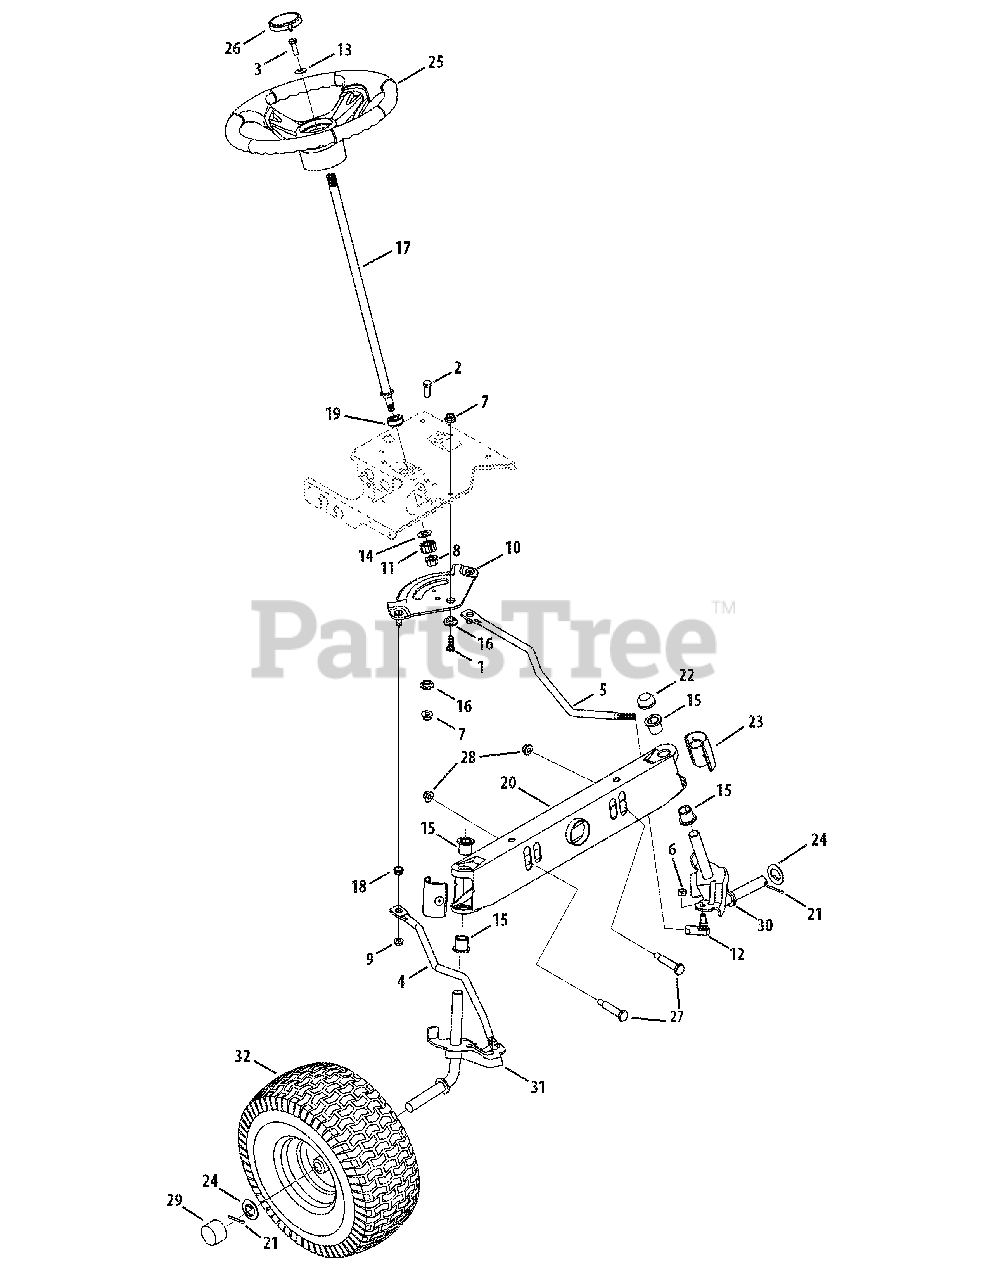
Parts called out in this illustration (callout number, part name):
1	Hex Screw, 3/8-16, 1.00, Gr5
2	Hex Screw, 3/8-16, 1.00, Gr5
3	Hex Screw, 5/16-18, 1.00, Gr5
4	Link, Drag, RH
5	Link, Drag, LH
6	Nut, Hex Lock, 3/8-24
7	Nut, Flange Lock, 3/8-16, Grf
8	Nut, Flange Lock, 7/16-20
9	Nut, Flange Lock, 5/16-18, Gr5
10	Gear, Steering, 11/90 Ratio
11	Gear, Pinion, Steering
12	Ball Joint, 7/16-20, Lock
13	Washer, Flat, .406 x .875 x .105
14	Washer, Flat, .51 x 1.12 x .06
15	Flange Bearing
16	Spacer, Shoulder, .38 x 1.00 x .31
17	Shaft, Steering, .625 OD x 24.25
18	Plastic Bushing .380 ID
19	Hex Flange Bearing
21	Cotter Pin, 5/32 x 1.25 (Cast Axle)
22	Push Cap, 3/4
23	Pivot Bar End Cap w/ fitting
24	Flat Washer, .781 x 1.59
25	Steering Wheel
26	Steering Wheel Cap, Sprig Logo
27	Shoulder Bolt, .5 x 2.38, 3/8-16
28	Flange Lock Nut, 3/8-16
29	Hub Cap, Standard
30	LH Axle Assembly, .750
31	RH Axle Assembly, .750
